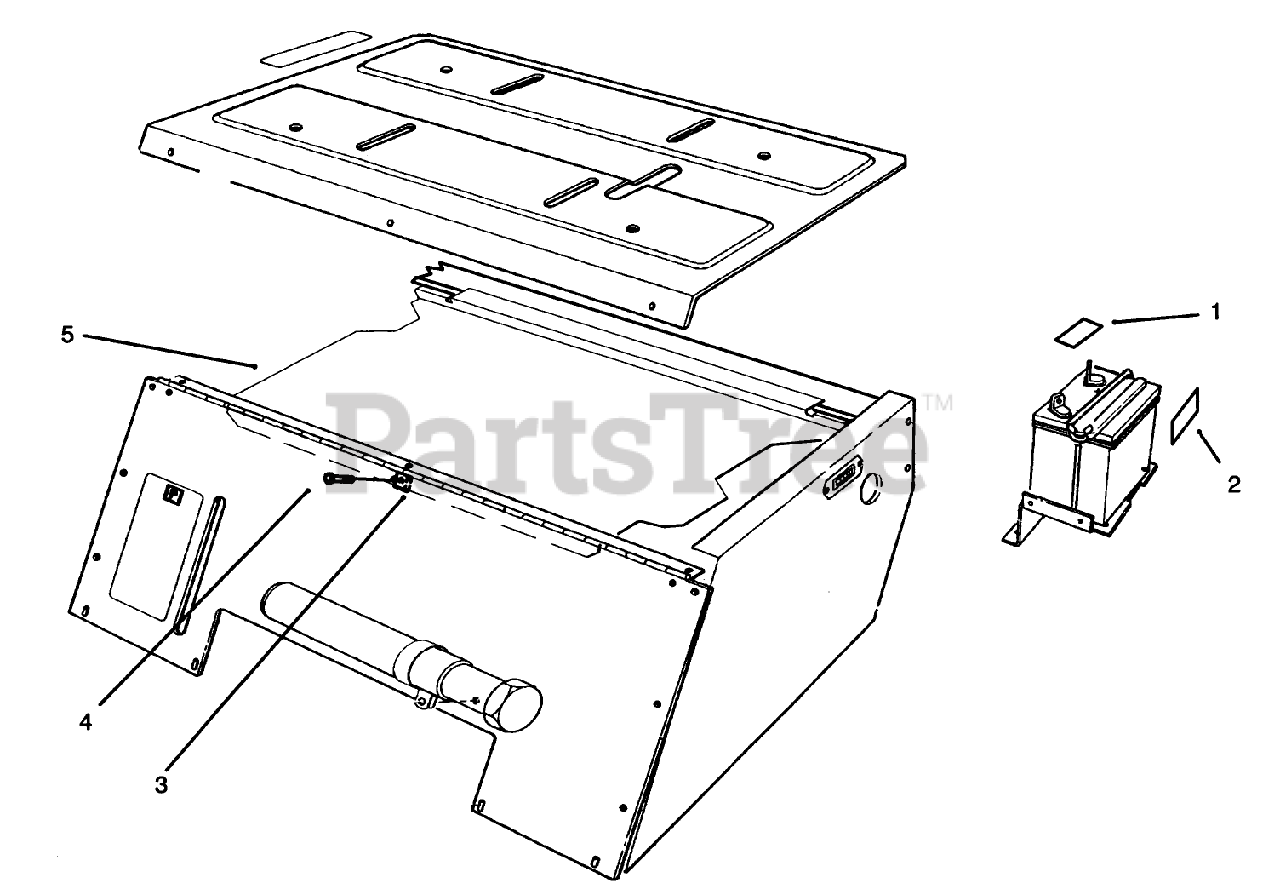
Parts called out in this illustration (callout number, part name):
1	DECAL-BATTERY
2	DECAL-DANGER
3	NUT-SPEED
4	SCREW-HH
5	Cover-Belt
